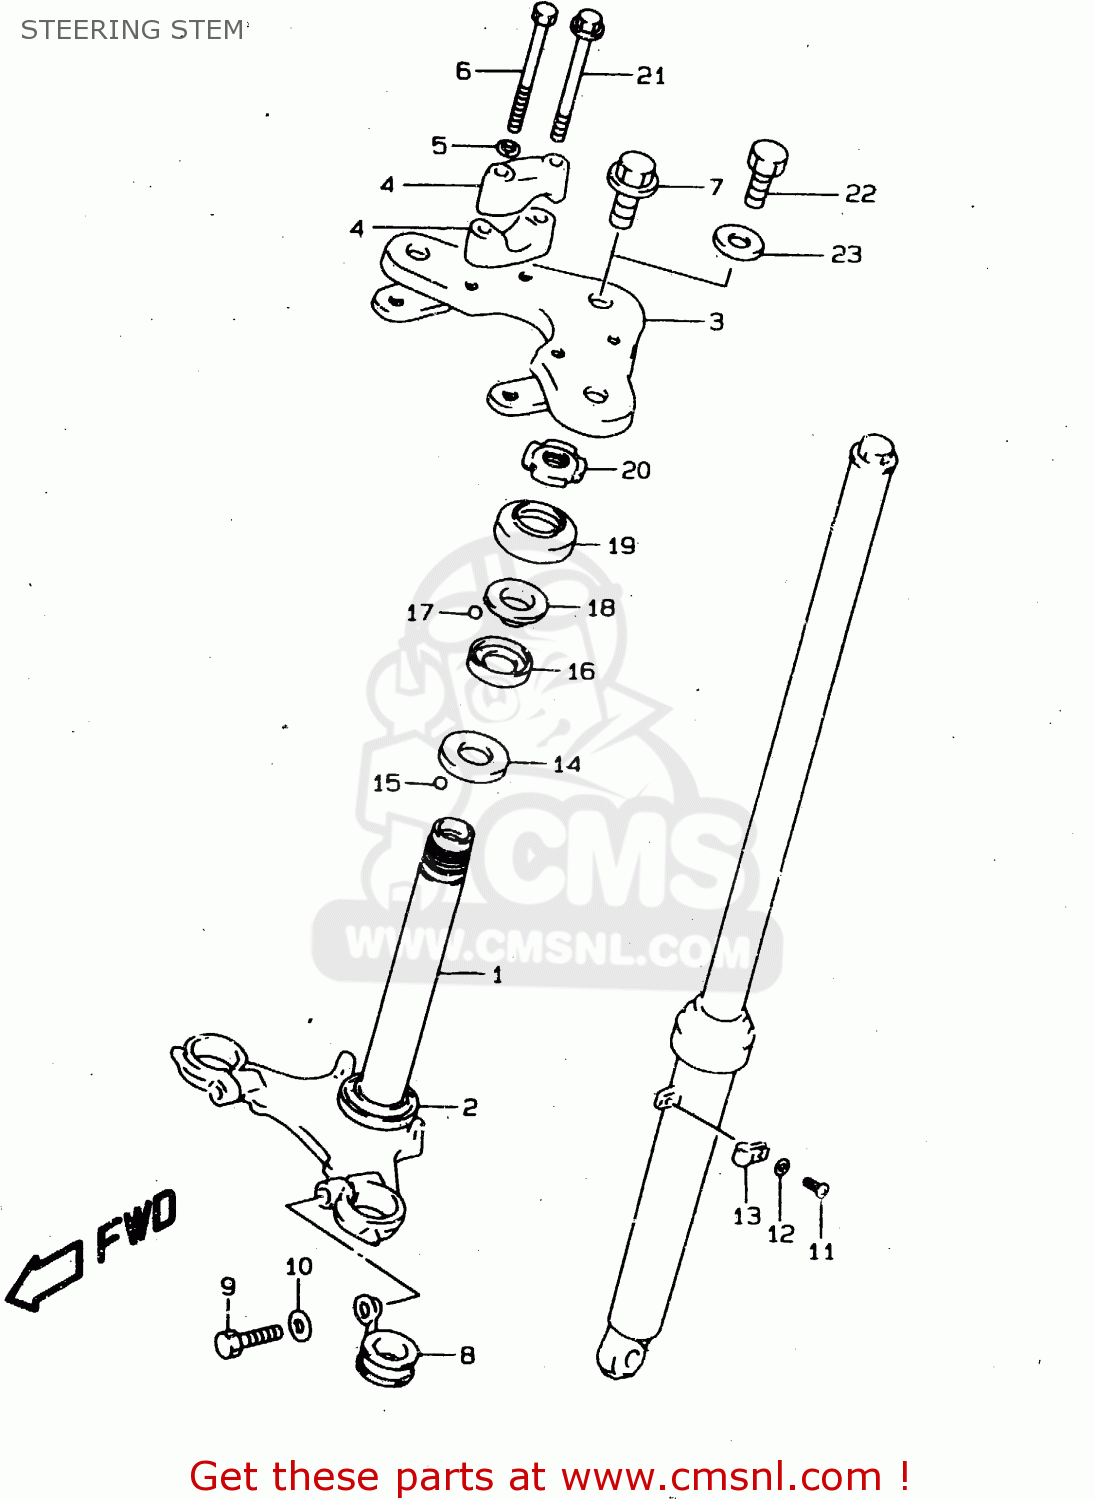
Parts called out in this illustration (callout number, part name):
1	STEM,STEERING
2	RACE,STEERING OUTER LWR
3	HEAD,STEERING STEM
4	HOLDER,HANDLE UPR
5	WASHER
6	BOLT
7	BOLT
8	CLIP
9	BOLT
10	WASHER,LOCK
11	SCREW
12	WASHER,LOCK
13	CLIP,FR BRAKE CABLE
14	LACE,STEERING INNER LWR
15	BALL
16	RACE,STEERING INNER UPR
17	BALL
18	RACE,STEERING OUTER UPR
19	DUST SEAL,STEERING UPR
20	NUT,STEERING STEM(25X44X10)
21	BOLT
22	BOLT
23	WASHER(10.5X30X2.3)
